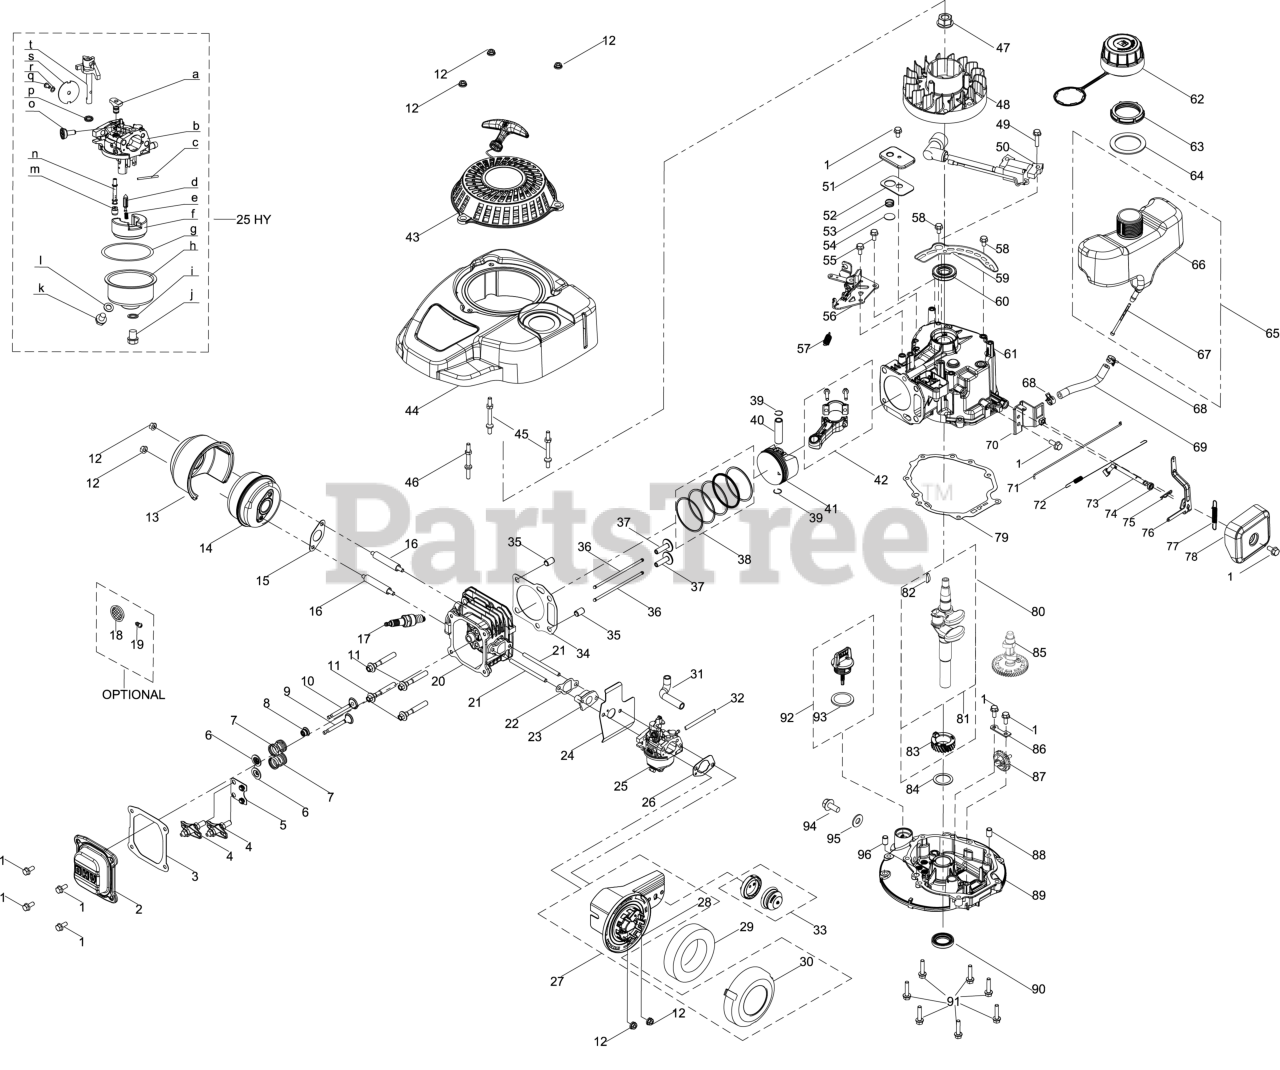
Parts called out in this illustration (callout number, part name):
1	BOLT M6-1 x 14 GR8.8
2	VALVE COVER
3	VALVE COVER GASKET
5	PUSH ROD GUIDE
6	VALVE RETURN SPRING
7	VALVE SPRING
8	INTAKE VALVE SEAL
9	EXHAUST VALVE
10	INTAKE VALVE
11	SCREW M8 x 54 GR10
13	MUFFLER SHIELD
14	MUFFLER ASSEMBLY
15	MUFFLER GASKET
16	STUD M6-1 x 76
17	SPARK PLUG (F5RTC/RN11YC4/BPR5ES)
18	SPARK ARRESTOR
19	SCREW M3.5 x 9.5
20	CYLINDER HEAD
21	STUD M6 x 98
22	CARBURETOR INSULATOR GASKET
23	CARBURETOR INSULATOR
24	CARBURETOR GASKET
25	CARBURETOR
26	AIR FILTER BASE GASKET
27	AIR FILTER ASSEMBLY
28	AIR FILTER BASE
29	FOAM AIR FILTER
30	Not Serviceable/ Order Complete Assembly
31	BREATHER HOSE
32	PRIMER HOSE
33	PRIMER ASSEMBLY
34	CYLINDER HEAD GASKET
35	PIN (10MMx16MM)
36	PUSH ROD
38	PISTON RING SET
39	WRIST PIN CLIP
42	CONNECTING ROD ASSEMBLY
43	STARTER RECOIL ASSEMBLY
44	ENGINE SHROUD ASSEMBLY
45	STUD M6 x 75
46	STUD M6 x 73
47	FLYWHEEL NUT M14-1.5
48	ENGINE FLYWHEEL
49	BOLT M6-1 x 25 GR8.8
50	IGNITION COIL ASSEMBLY
51	BREATHER COVER PLATE
52	BREATHER COVER GASKET
53	BREATHER VALVE SPRING
54	BREATHER VALVE
55	BOLT M6-1 x 12 GR8.8
56	ENGINE BRAKE ASSEMBLY
57	BRAKE SPRING
58	BOLT M6-1 x 10 GR8.8
59	SHROUD COVER PLATE
62	FUEL CAP W/TETHER
63	FUEL TANK NUT
64	FUEL TANK GROMMET
65	Not Serviceable/ Components Only
66	FUEL TANK
67	FUEL FILTER
68	CARBURETOR HOSE CLAMP
70	COMPONENT BRACKET
71	THROTTLE LINKAGE
72	THROTTLE LINKAGE SPRING
73	GOVERNOR ARM SHAFT
76	GOVERNOR ARM ASSEMBLY
77	GOVERNOR SPRING
78	GOVERNOR SHIELD
79	CRANKCASE COVER GASKET
80	Not Serviceable/ Components Only
81	Crankshaft Assembly
82	WOODRUFF KEY
84	THRUST WASHER
85	CAMSHAFT
86	GOVERNOR GEAR MOUNTING PLATE
87	GEAR GOVERNOR
88	DOWEL PIN 7 X 14
89	CRANKCASE COVER
90	LOWER CRANKSHAFT SEAL
91	BOLT-M6-1 x 28 GR8.8
92	DIPSTICK ASSEMBLY
93	DIPSTICK O-RING
94	OIL DRAIN PLUG
95	FLAT WASHER
96	DOWEL PIN 9 X 14
